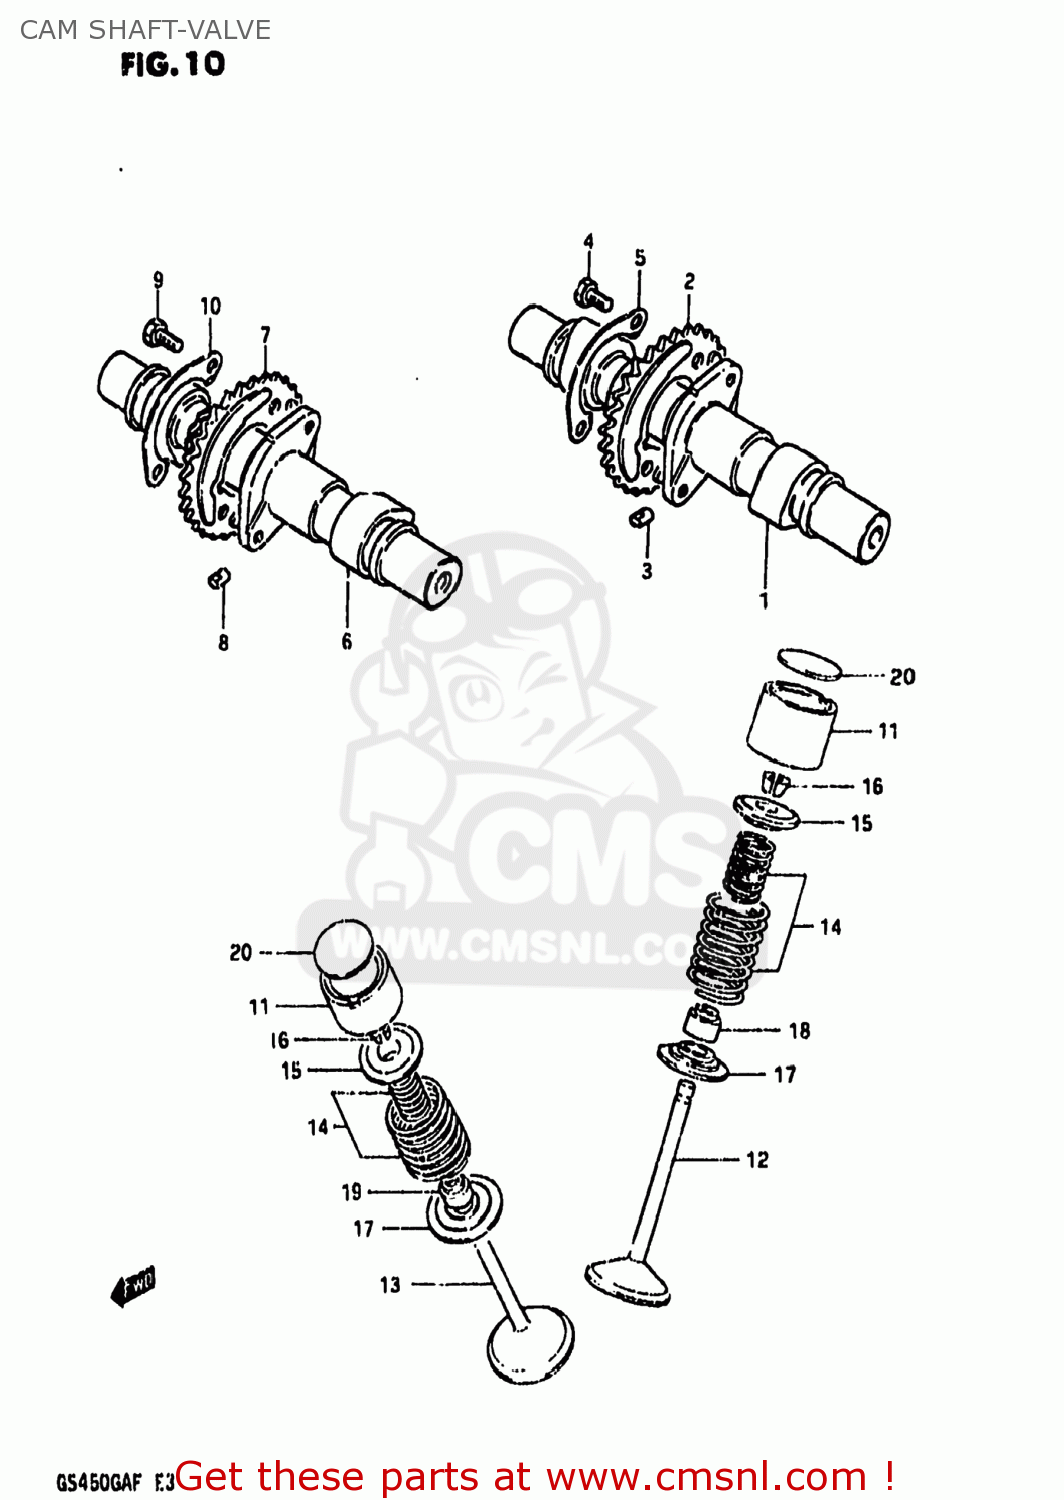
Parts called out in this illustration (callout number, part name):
1	CAMSHAFT
2	SPROCKET,CAMSHAFT
3	PIN,SPROCKET
4	BOLT(6X12.5)
5	WASHER,CAM CHAIN SPROCKET
6	CAMSHAFT,EXHAUST
7	SPROCKET,EXHAUST CAM(NT:30)
8	PIN,SPROCKET
9	BOLT(6X12.5)
10	WASHER,CAM CHAIN SPROCKET
11	TAPPET,INTAKE
12	VALVE,INTAKE
13	VALVE,EXHAUST
14	SPRING SET,VALVE
15	RETAINER,VALVE SPRING
16	COTTER VALVE
17	SEAT,VALVE SPRING
18	SEAL,OIL(7X14.4X9)
19	SEAL,OIL(7X14.5X10.5)
20	SHIM,TAPPET
21	SHIM SET,TAPPET
22	CASE
